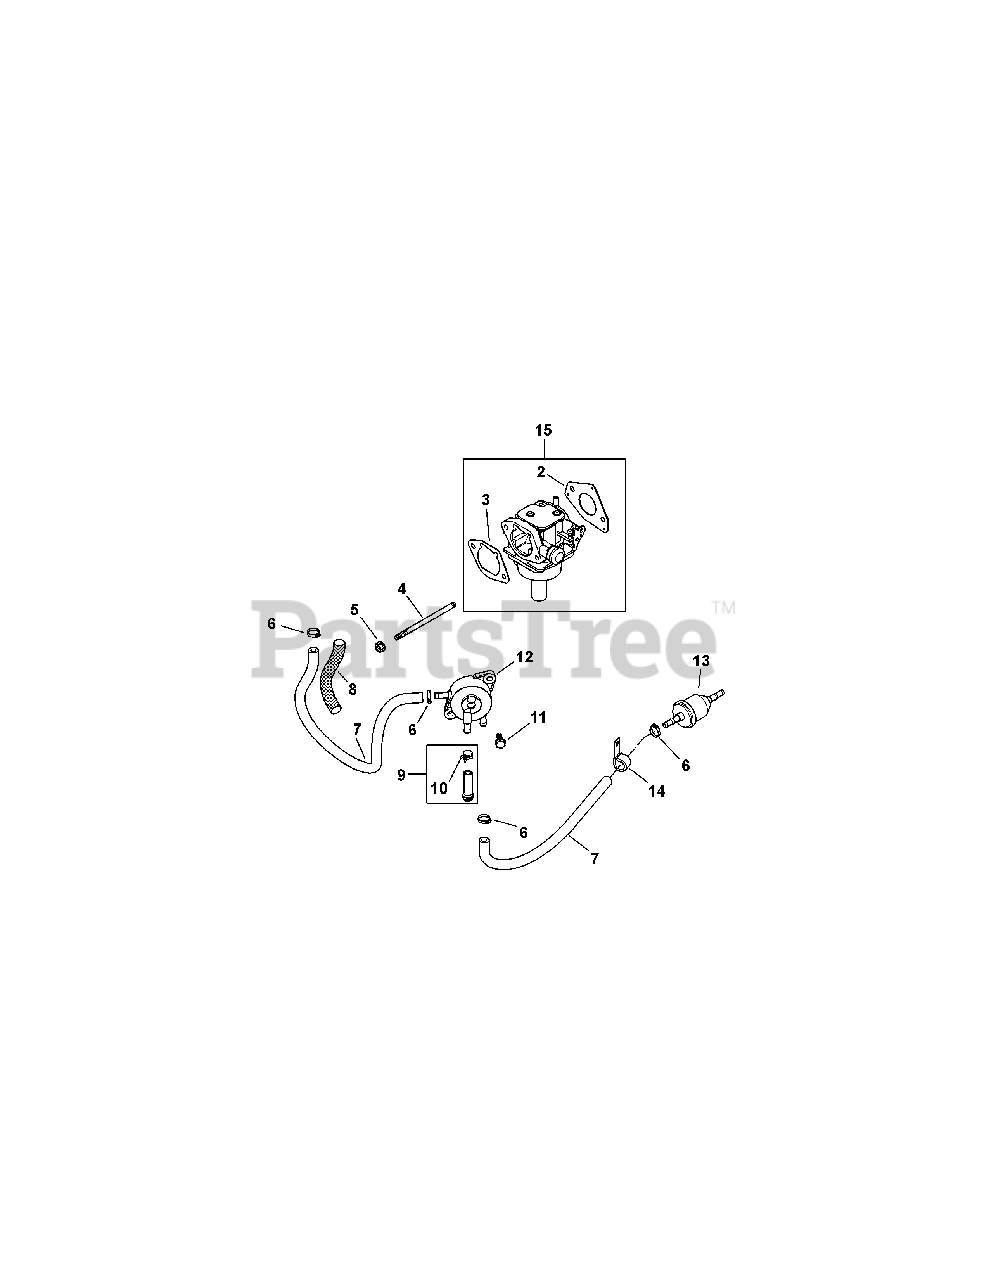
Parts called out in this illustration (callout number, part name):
2	Carburetor Gasket
3	Air Cleaner Base Gasket
4	Stud, M6 X 1.0 X 106
5	Flg. Nut, M6 X 1.0
6	Hose Clamp, 1/2
7	Fuel Line
8	Anti Abrasion Sleeve
9	Pulse Pump Hose (Inc. 10)
11	Tap Screw, M6 X 1.7 X 18
15	Carburetor Kit, 19mm KEIHIN (Inc.2 & 3)
